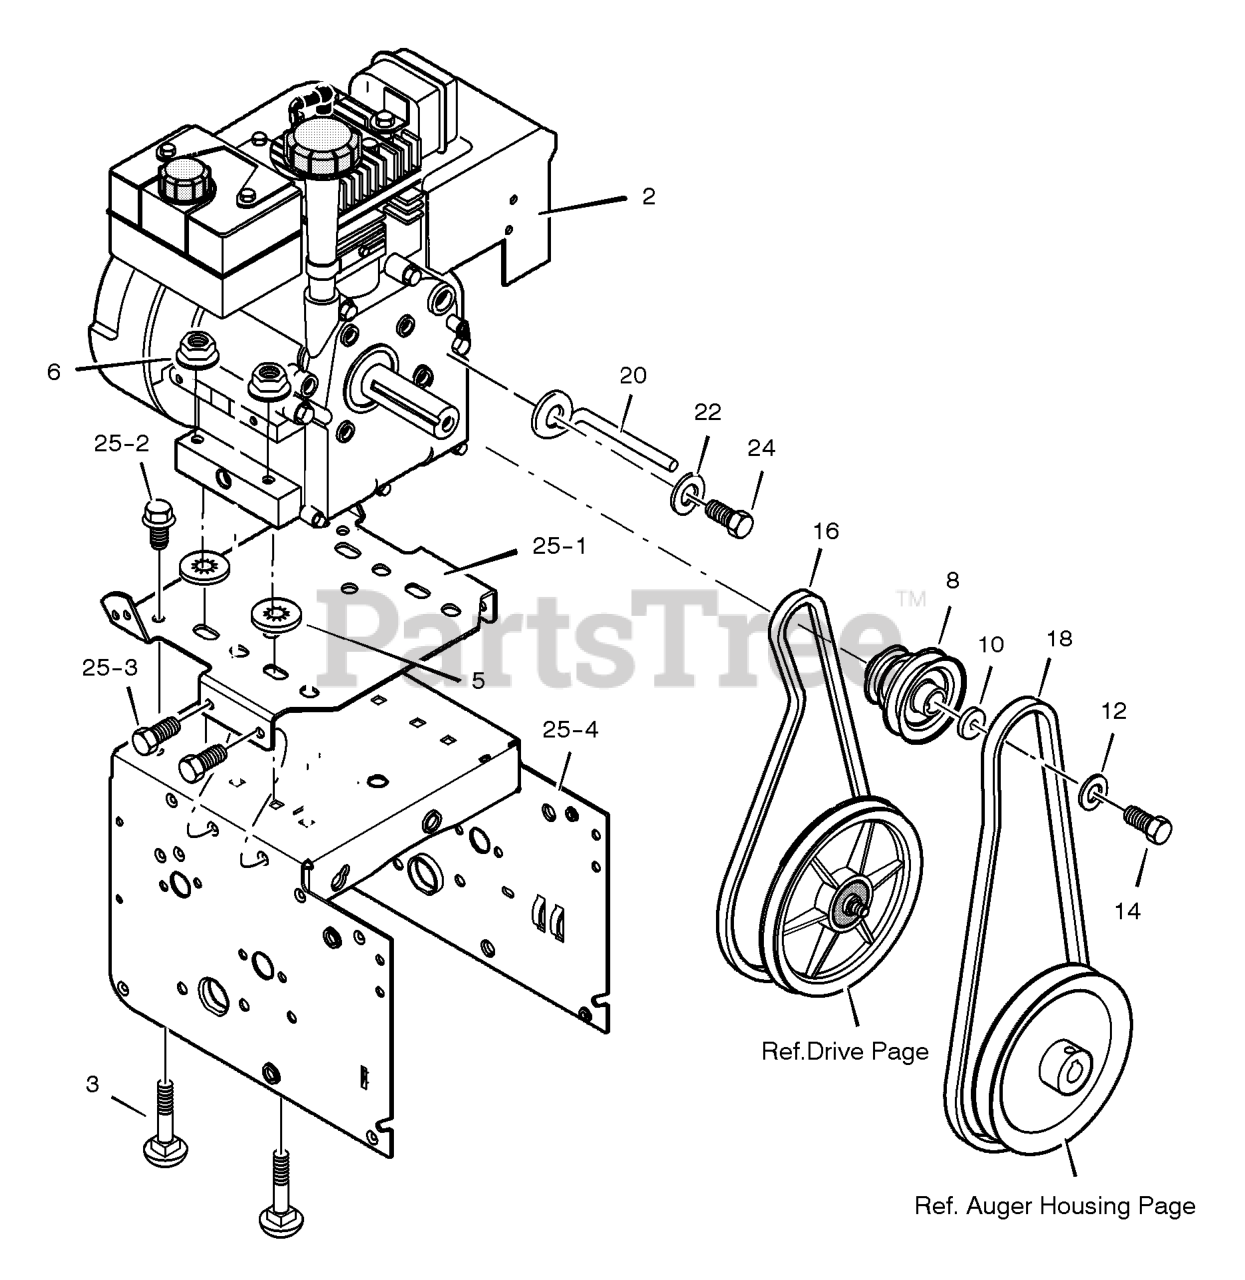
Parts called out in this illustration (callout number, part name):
2	ENGINE
3	BOLT, CARRIAGE 5/16-18
5	RETAINER, PUSH
6	NUT, HEXWDFLLK 5/16-18
8	PULLEY, ENGINE
10	WASHER
12	WASHER,HVSPTLK .38ID
14	SCREW, 3/8-24 x 1.00
16	BELT, V 3L 33.13LG
18	BELT, V 4L 38.1MF16" 5-10
20	GUIDE, BELT
22	WASHER, SPTLK .31X.58X.08
24	SCREW, 5/16-24 x 0.75
25	FRAME ASSEMBLY
25-1	PLATE, ENGINE MOUNT
25-2	SCREW, TAP 1/4-20 X .63
25-3	SCREW, TAP 5/16-18 X .50
25-4	FRAME, MOTOR BOX
